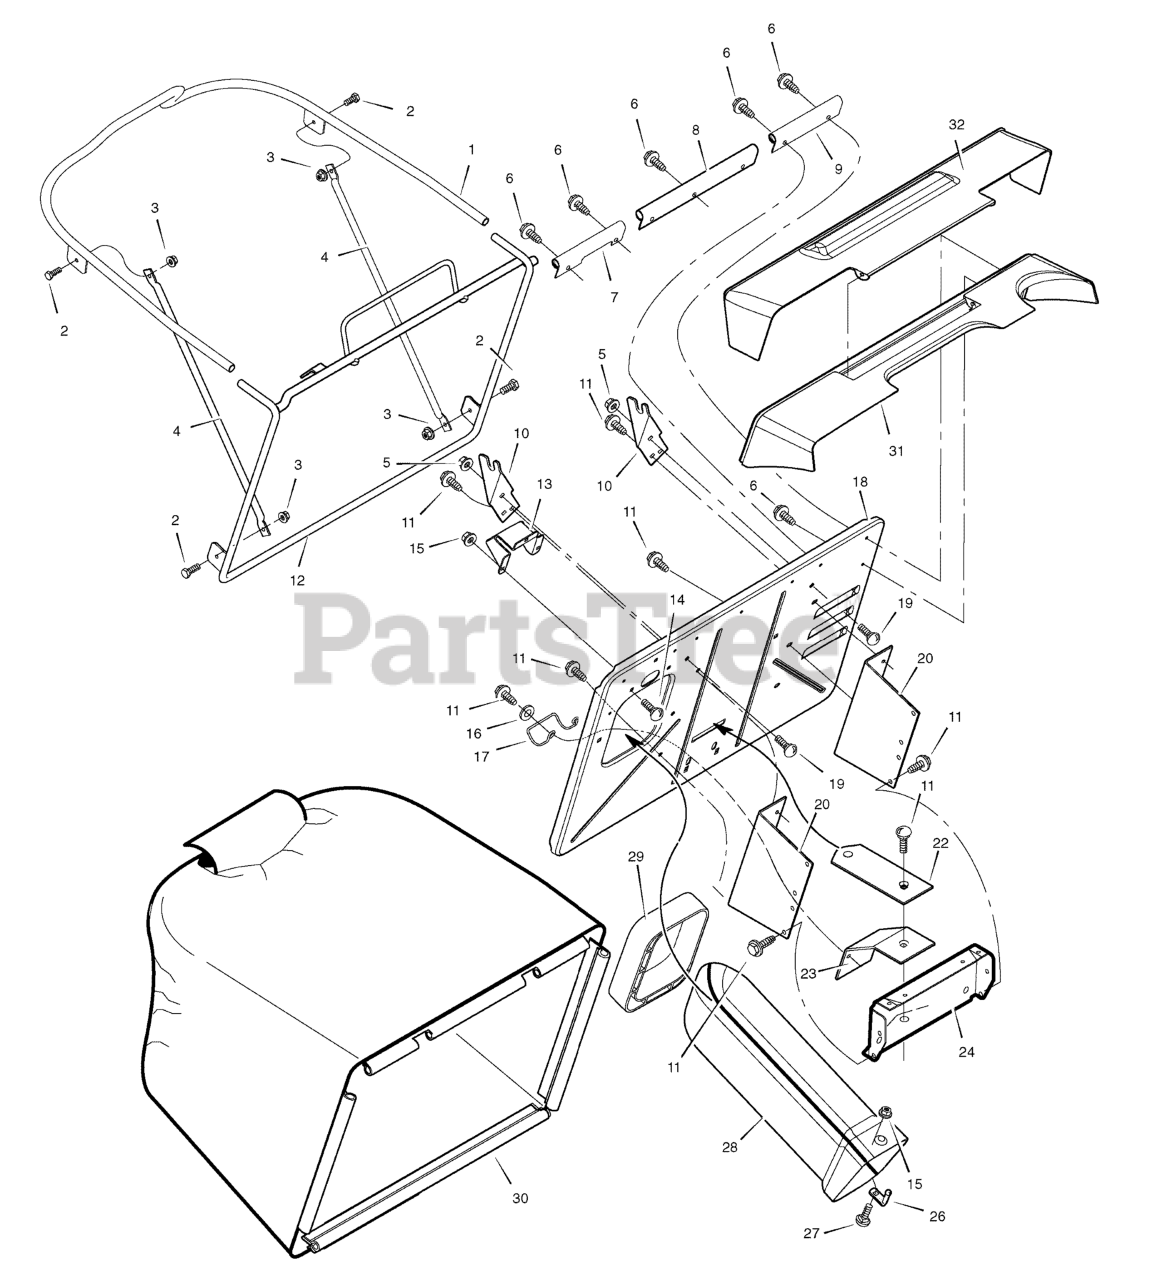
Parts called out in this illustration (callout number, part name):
1	TUBE, Top
2	BOLT
3	NUT
4	STRUT, Bag
5	NUT, Flange
6	FASTENER, Panel
7	SEAL, Bag (Right End)
8	SEAL, Bag (Center)
9	SEAL, Bag (Left End)
12	ASSEMBLY, Bag Frame
13	BRACKET, Switch
14	BOLT, Carriage
15	NUT, Flange
16	WASHER
17	LATCH, Spring
18	PANEL, Rear
19	BOLT, Carriage
20	BRACKET, Bagger Mounting
22	PLATE, Hitch
23	BRACKET, Lower Mounting
24	PLATE, Hitch
26	PIN, Latch
27	BOLT, Carriage
28	TUBE, Connecting
29	GROMMET, Extension Tube
30	BAG, Grass
31	BAGGER COVER, Front
32	BAGGER COVER, Rear
